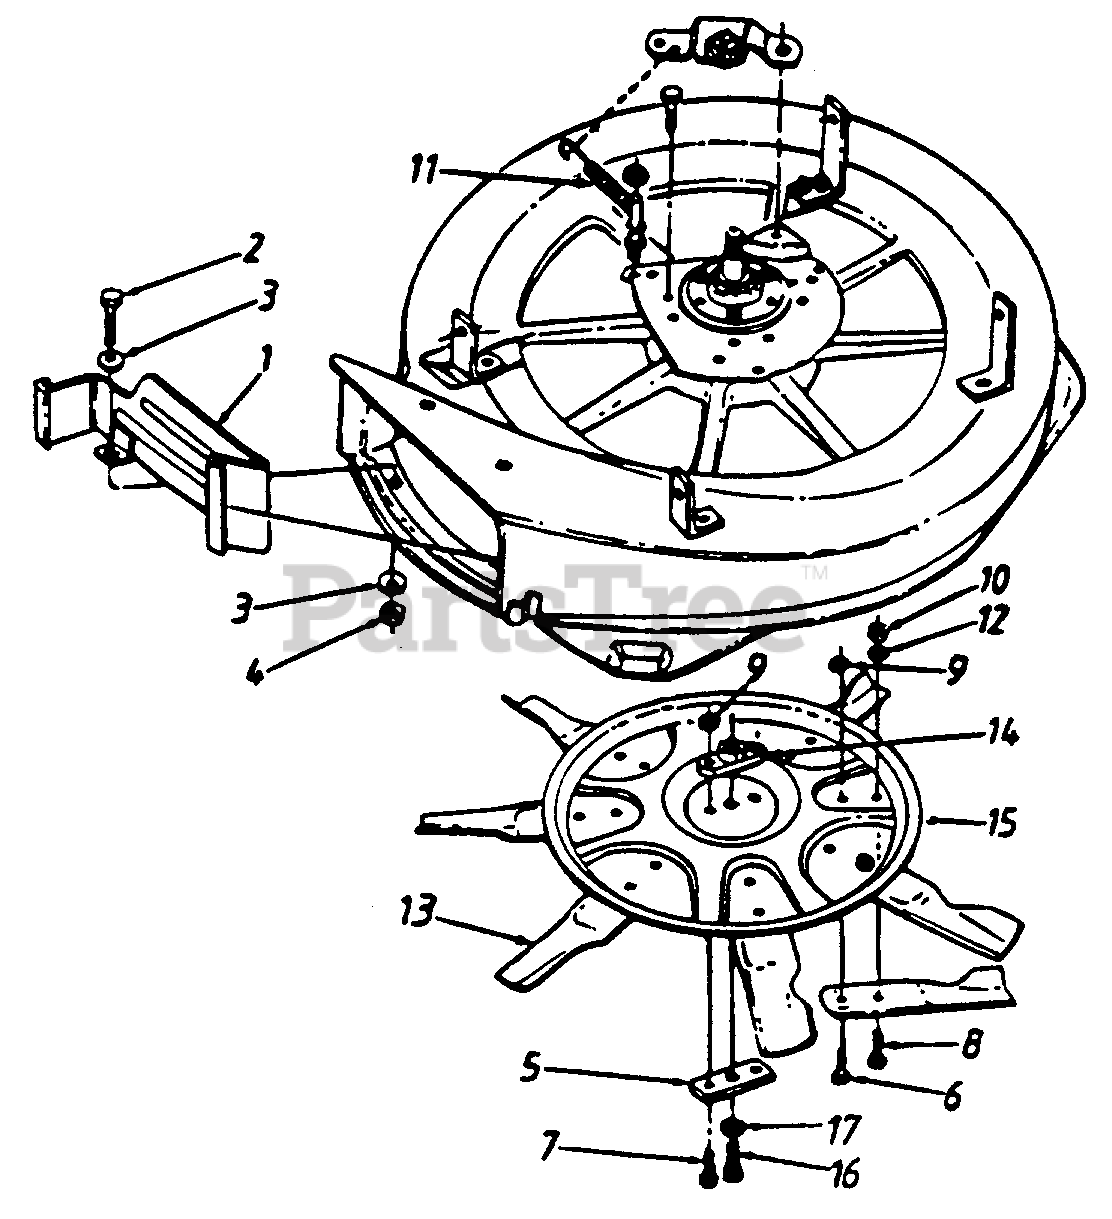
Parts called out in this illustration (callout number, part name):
1	Mulching Baffle Ass'y.
2	Hex Bolt 5/16-18 x .5"
3	Bell-Wash. .325" I.D.
4	Hex L-Nut 5/16-18 Thd.
7	Hex Bolt 5/16-24 x 1.25" Lg. (Gr. 5)
8	Hex Bolt 3/8-24 x .88" Lg.
9	Hex L-Nut 5/16-24 Thd.
10	Hex L-Nut 3/8-24 Thd. (Gr. 5)
11	Extension Spring 3.2" Lg.
12	Fl-Wash. .406" I.D. x .75"
13	30" Mulching Blade Tip
14	Blade Adapter
15	30" Mulching Blade Tip
16	Hex Bolt 3/8-24 x 1.25" Lg. (Gr. 8)
17	L-Wash. 3/8" I.D.
